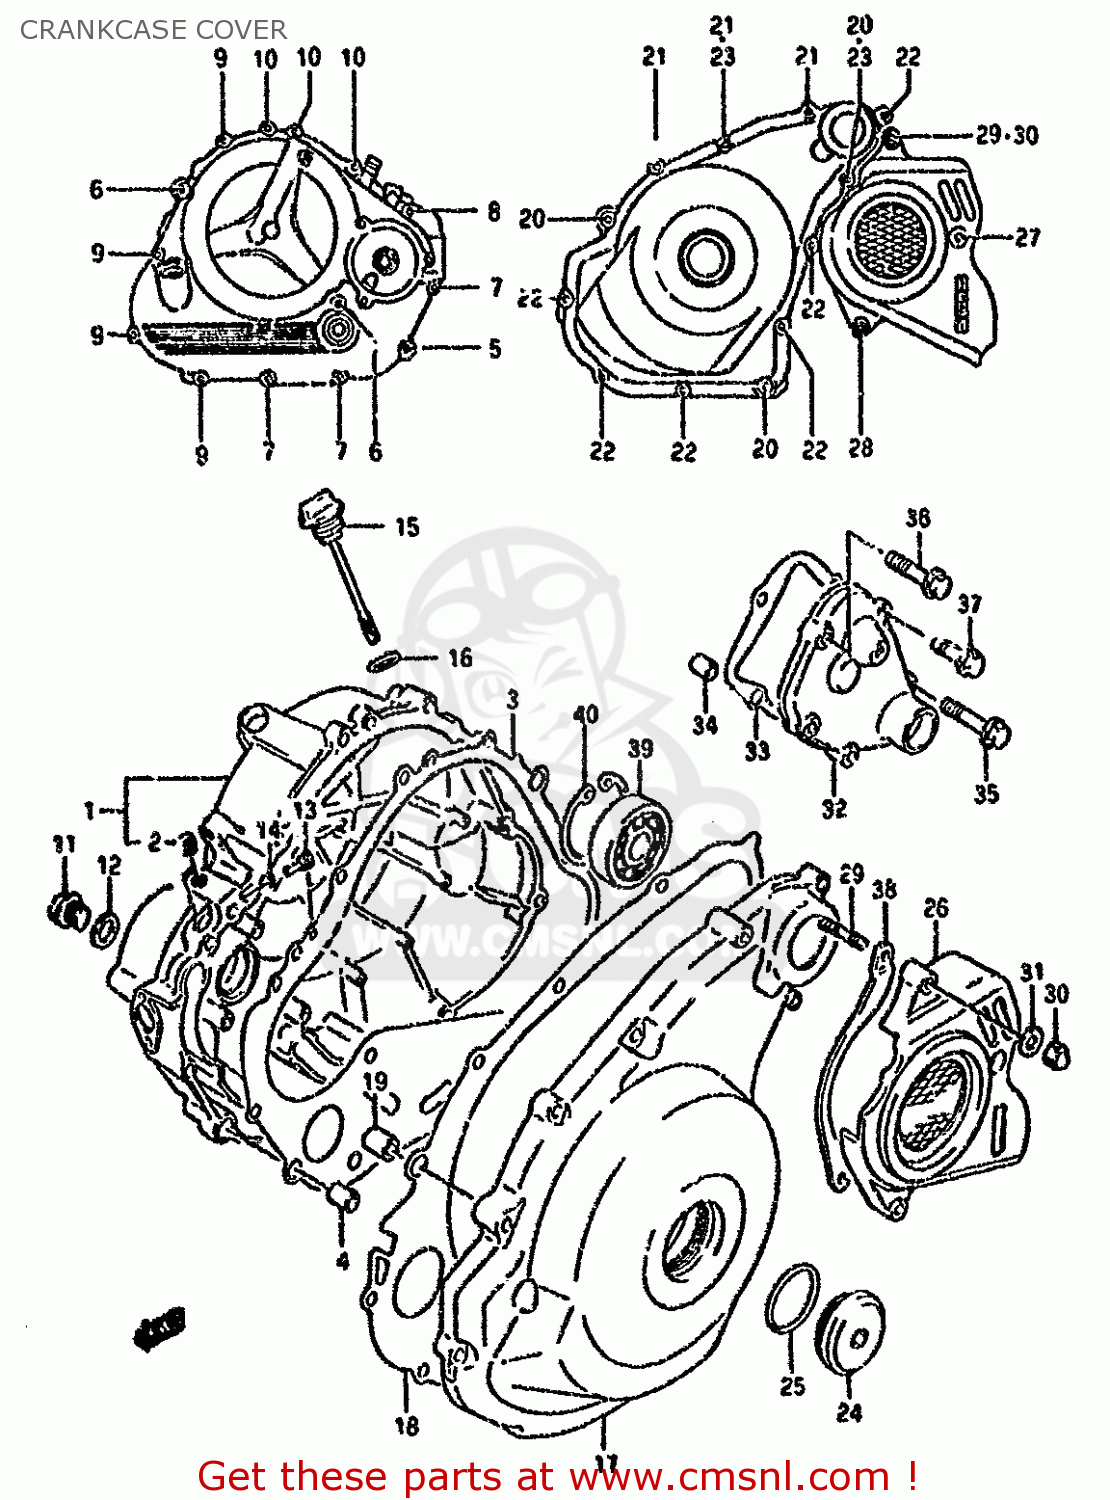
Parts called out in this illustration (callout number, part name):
1	COVER,CLUTCH
2	PLUG
3	GASKET,CLUTCH COVER (NAS)
4	PIN
5	BOLT
6	BOLT
7	BOLT
8	BOLT
9	BOLT
10	BOLT
11	PLUG(14X12)
12	GASKET(13.8X18.8X4.8) (NAS)
13	JET
14	O RING(D:1.2,ID:4)
15	GAUGE,OIL LEVEL
16	O RING(D:3.1,ID:16.8)
17	COVER, MAGNETO
18	GASKET,MAGNETO COVER (NAS)
19	PIN
20	BOLT
21	BOLT
22	BOLT
23	GASKET(5.8X13X1.2) (NAS)
24	PLUG(SILVER)
25	O RING(D:3.1,ID:32.7)
26	COVER,ENGINE SPROCKET
27	BOLT
28	BOLT
29	BOLT,STUD
30	NUT
31	WASHER
32	COVER,GEAR SHIFT
33	GASKET,GEAR SHIFT COVER (NAS)
34	PIN
35	BOLT
36	BOLT
37	BOLT
38	PLATE,FR CHAIN GUIDE
39	BEARING(12X28X8)
40	CIRCLIP
